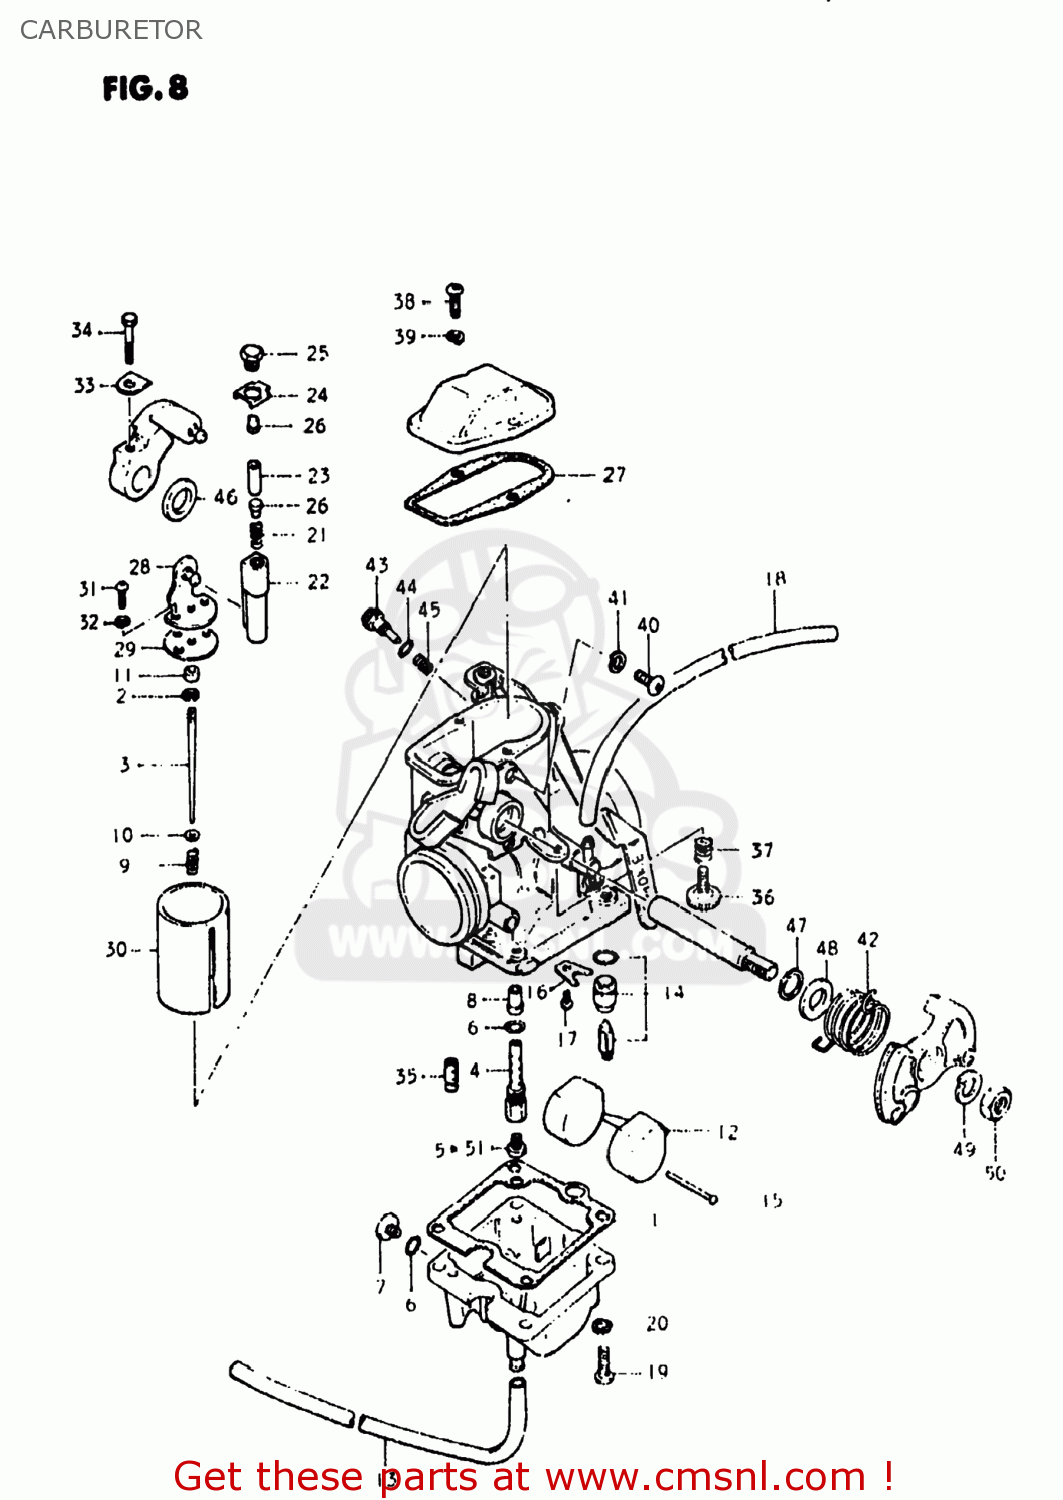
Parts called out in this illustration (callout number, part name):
1	GASKET,FLOAT CAHMBER (NAS)
2	CLIP
3	NEEDLE JET
4	PIPE,BLEEDER
5	JET
6	O RING
7	SCREW
8	JET,NEEDLE
9	SPRING
10	WASHER,JET NEEDLE
11	RING
12	FLOAT
13	HOSE
14	VALVE ASSY,NEEDLE
15	PIN,FLOAT
16	PLATE
17	SCREW 4X6
18	HOSE
19	SCREW
20	LOCK WASHER
21	SPRING,CARBURETOR
22	LEVER ASSEMBLY
23	SPRING
24	PLATE,CARBURETOR
25	SCREW
26	PIN,CARBURETOR
27	GASKET,MIXING CHAMBER
28	BRACKET,CARBURETOR
29	PLATE,THROTTLE VALVE
30	VALVE,THROTTLE
31	SCREW
32	LOCK WASHER
33	RING
34	BOLT
35	JET
36	ADJUSTER
37	SPRING,THROTTLE SCREW
38	SCREW
39	LOCK WASHER
40	SCREW
41	LOCK WASHER
42	SPRING,THROTTLE VALVE
43	SCREW,PILOT AIR ADJUSTING
44	O RING
45	SPRING
46	RING
47	SEAL
48	RING
49	LOCK WASHER
50	NUT
51	JET
